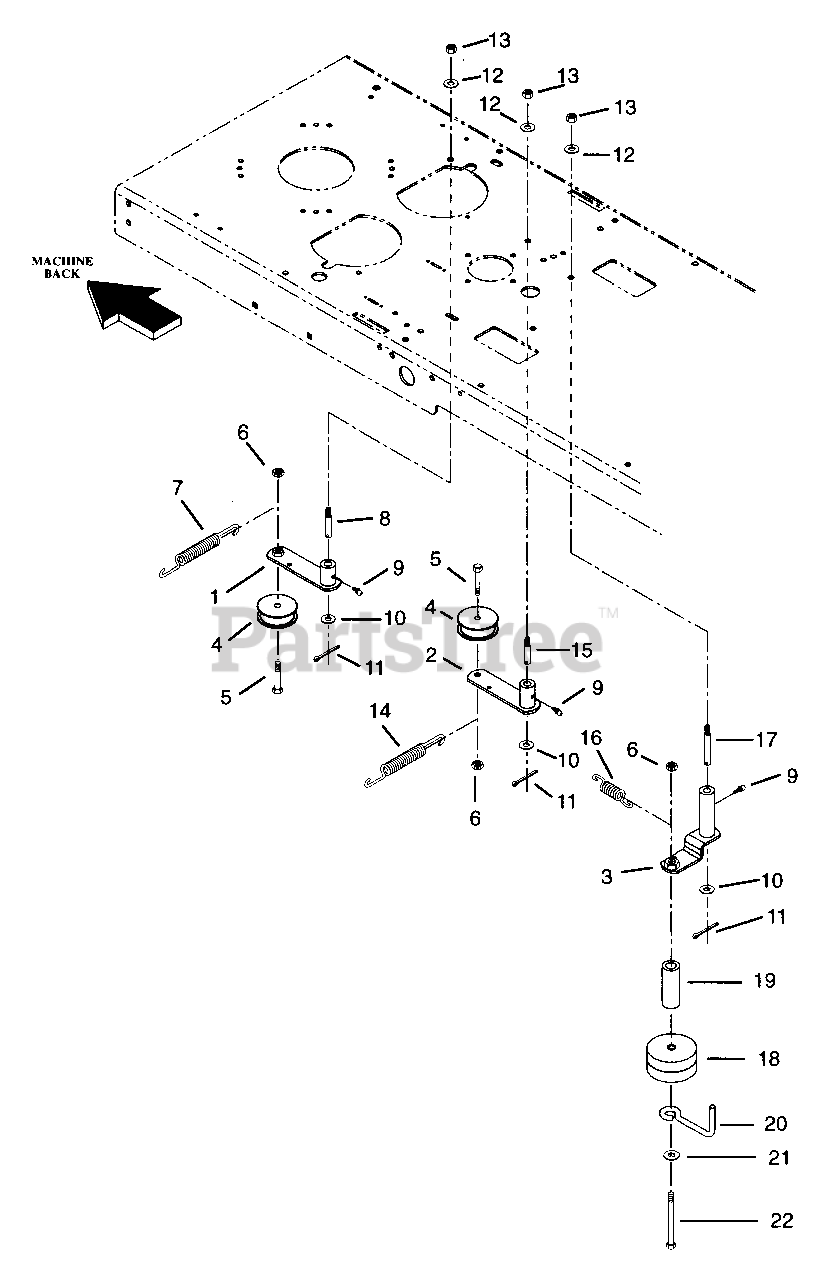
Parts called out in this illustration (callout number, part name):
1	IDLER ARM -TRANS/ENG (SHORTER)
2	IDLER ARM -CLUTCH/ENG (LONGER)
3	ARM - IDLER PIVOT
4	IDLER - 2.25X.87
5	BLT-HEX .38-16X2.00 PL GR5
6	NUT-LK-NYL .375-16 PL
7	SG-TENS .085X.60X5.13 WLD8.3
8	SHOULDER STUD
9	FTG-LUBE .25-28X.256 YWZC
10	WSHR-FL-STL .520X.827X.062 YZ
11	PIN-COTR .18X1.25 PL
12	WSHR-FL-STL .390X.750X.125 PL
13	NUT-LK-NYL .375-16 PL
14	SG-TENS .095X.62X9.25 WLD ??
15	SHOULDER STUD
16	SG-TENS .090X.75X3.50 WLD 34
17	SHOULDER STUD
18	IDLER-FLAT 3.25 X .38 NWHAMSHR
19	TUBE .380 X .625 X 1.620
20	FINGER - BELT
21	WSHR-FL-STL.406X.812X.065PL
22	BLT-HEX .375-16X4.50 GR2 FLTHD
